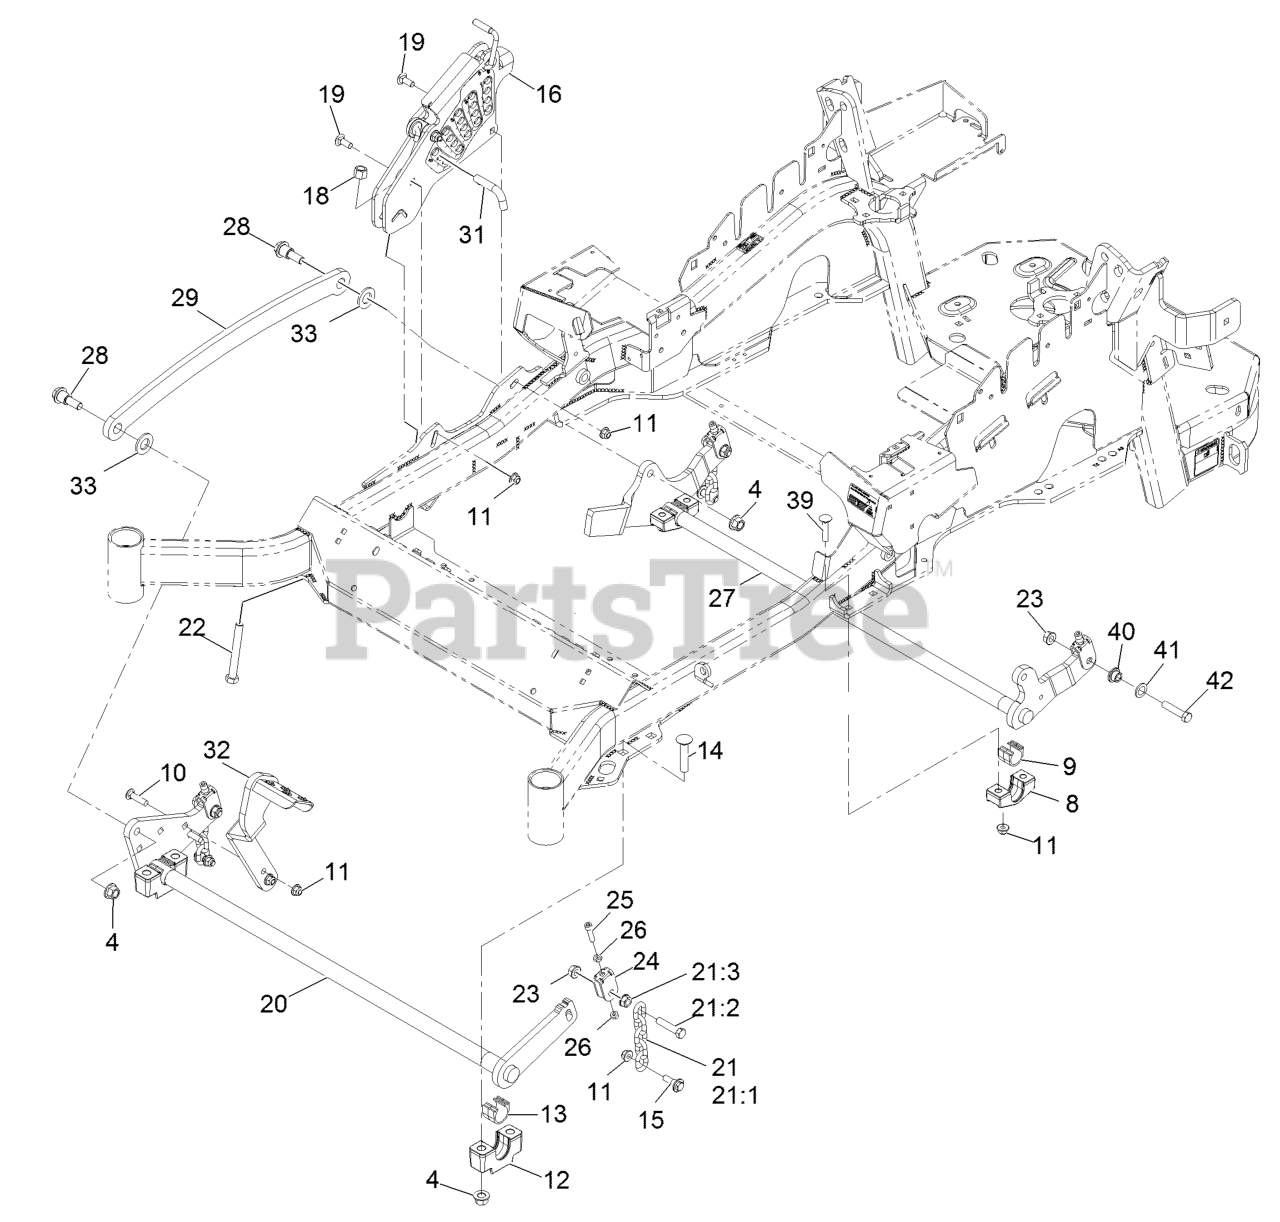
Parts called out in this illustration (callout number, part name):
4	Nut-Lock 1/2-13
9	BEARING-CROSS SHAFT, REAR
10	SCREW-CARR
11	NUT-HF, NI
12	SUPPORT-CROSS SHAFT, BEARING
13	BEARING-CROSS SHAFT, FRON
14	Bolt-Carriage 1/2-13 X 2 1/2 Spl Neck
15	SCREW-SHOULDER, HHF
16	HEIGHT-OF-CUT ASM
18	NUT-LOCK, NI
19	BOLT-CARR
21	DECK LIFT CHAIN ASM
21:1	CHAIN-LIFT, DECK
21:2	SCREW-HH
22	BOLT-TAP
24	YOKE-ADJUST, DECK
25	SCREW-HSH
26	NUT-JAM
27	LIFT-DECK, REAR
28	SCREW-SHOULDER, HHF 1/2-13 X 1.12
29	LINK-LIFT, DECK
31	PIN-HOC
32	FOOT LEVER
33	WASHER-FLAT
39	SCREW-CARR
40	BUSHING-FLANGED
41	WASHER-FLAT
42	SCREW-HH
